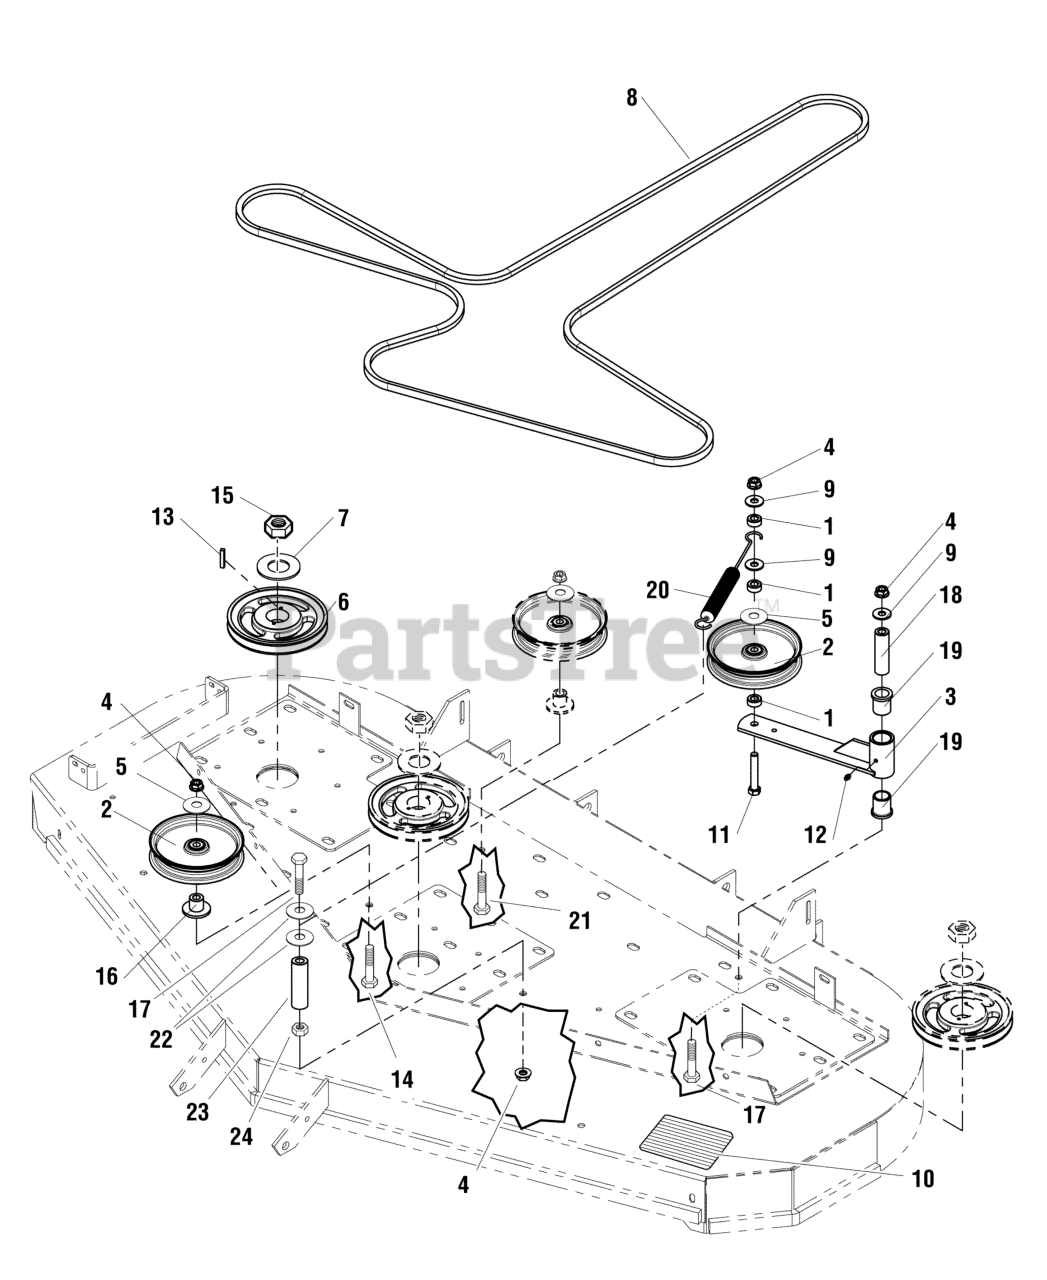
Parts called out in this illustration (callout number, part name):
1	SPACER, .52 X 1.00 X .44
3	WELD, IDLER ARM - RED
4	NUT, Hex Flange, Nylock, 1/2-13
5	SHIELD, PULLEY BEARING
6	PULLEY, 7.15 OD X 25MM BORE (BC72)
7	WASHER, 3/4 BELLEVILLE
8	BELT, # 7-6212
9	WASHER, 1/2 USS
10	SAFETY WALK, 9.75 X 6.00
11	BOLT, 1/2-13 X 3-1/2, HEX HD, GD5, CZ (SV)
12	GREASE FITTING, 1/4-28 STR
13	KEY 1/4 SQ X 1-1/2 LONG
14	BOLT, 1/2-13 X 2-3/4 GD5 CZ
15	NUT, 3/4-16 HEX
16	IDLER MOUNT
17	BOLT, 1/2-13 X 4-1/2 GD5
18	SPACER, .52 X 1.00 X 3.50
19	BUSHING, FLANGE
20	SPRING, EXTENSION, SWIVEL END
21	BOLT, 1/2-13 X 3" GD5 CZ
22	WASHER, 1/2 GD9 YZ
23	HOSE, 1/2" PUSH-ON, 2.25"
24	NUT, 1/2-13 HEX
